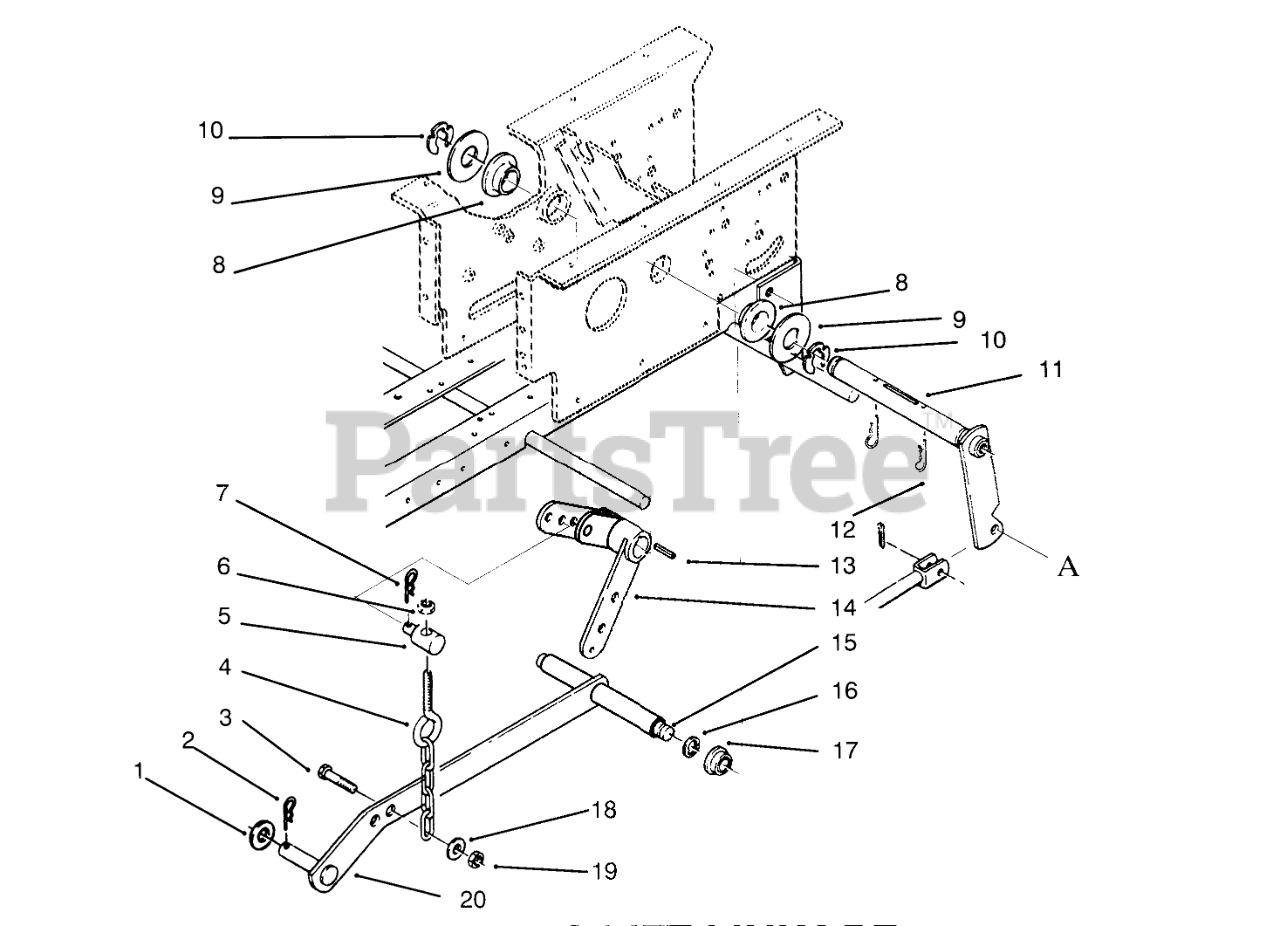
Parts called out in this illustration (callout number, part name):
1	WASHER-FLAT
2	PIN-HAIR
3	SCREW-HH
4	CHAIN-LIFT
5	TRUNNION
6	NUT-LOCK, NI
7	PIN-HAIR
8	BEARING-FLANGE
9	WASHER-FLAT
10	RING-RETAINING
11	WLDMT-LIFT ARM
12	PIN-HAIR
13	KEY-SQUARE
14	WLDMT-LIFT LEVER
15	PIN-PIVOT
16	RING-RETAINING, EXTERNAL
17	BUSHING
18	WASHER-PLAIN
19	NUT-LOCK, NI
20	Bar-Lift
